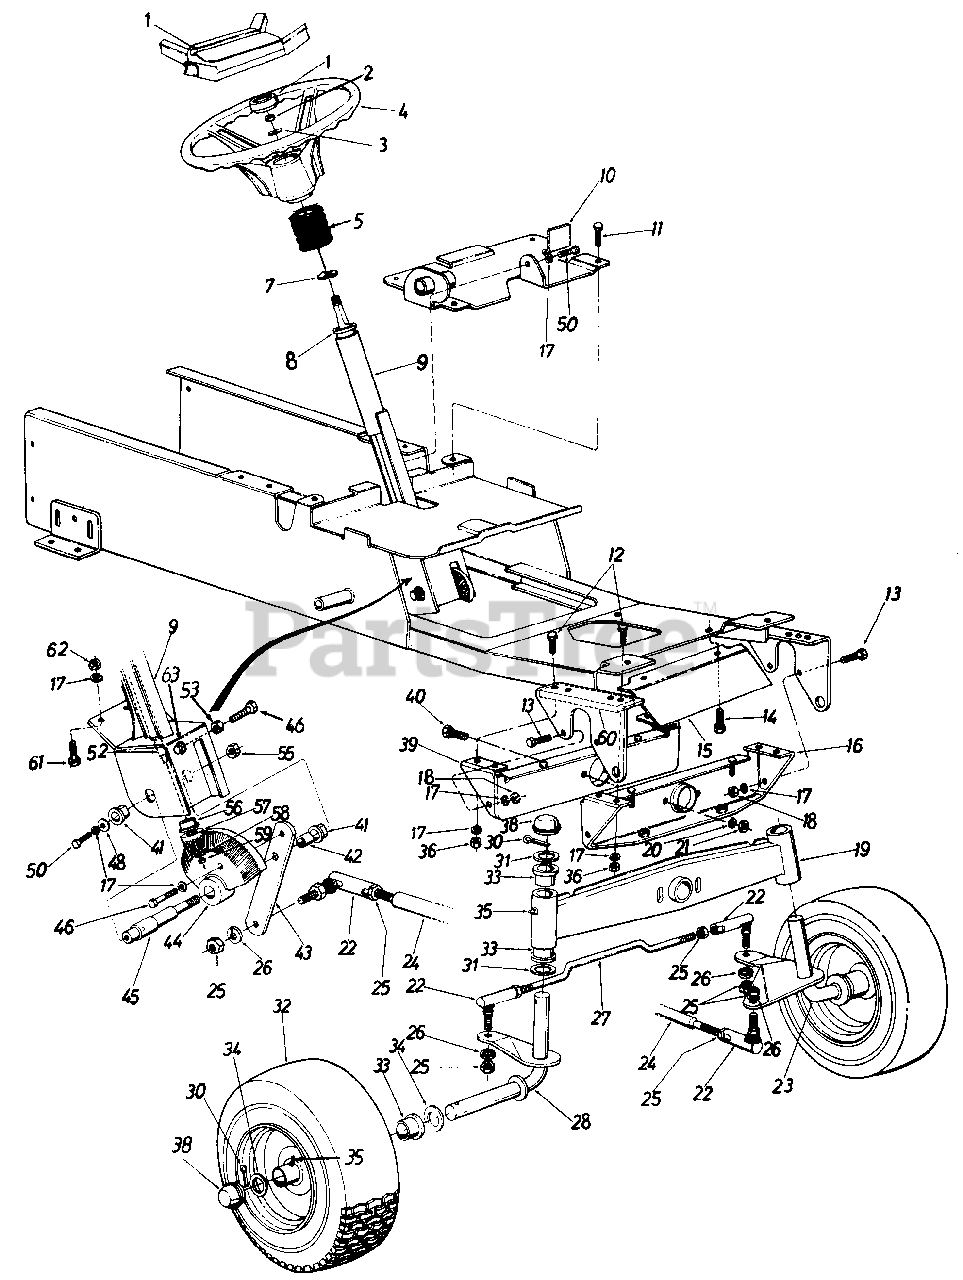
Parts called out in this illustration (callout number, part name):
1	Steering Wheel Cap
2	Hex Cent. L-Nut 5/16-24 Thd.
3	Bell-Wash. 5/16" I.D.
4	Steering Wheel
5	Steering Bellow
7	Wave Wash. .660" I.D. x .88" O.D.
8	Ball Brg. .63" I.D. x 1.38" O.D.
10	Dash panel Base Plate Ass'y.
11	Hex Self-Tap Scr. 3/8-16 x .75" Lg.
12	Hex Bolt 3/8-16 x 1.50" Lg.
13	Hex Bolt 3/8-16 x 1.00" Lg.
14	Hex Wash. S.F. Tap Scr. 3/8-16 x 1.25" Lg.
18	Hex Nut 3/8-16 Thd.
19	Pivot Bar Ass'y.
20	Bell-Wash. 3/8" I.D.
21	Hex Cent. L-Nut 3/8-16 Thd.
22	Drag Link End
23	Axle Ass'y. - L.H.
24	Drag Link
25	Hex Nut 1/2-20 Thd.
26	L-Wash. 1/2" I.D.
27	Tie Rod
28	Axle Ass'y. - R.H.
30	Cotter Pin 3/16" Dia. x 1.50" Lg.
31	Fl-Wash. 1.00" I.D. x 1.62" O.D.
33	Flange Brg. 1" I.D.
34	Fl-Wash. 1" I.D. x 1.25" I.D.
35	Grease Fitting
36	Hex Nut 3/8-16 Thd.
38	Dust Cover
41	Flange Brg. w/Flats .753" I.D.
42	Steering Gear Shaft Spacer
43	Steering Arm
44	Bevel Gear
45	Steering Gear Shaft
46	Hex Bolt 3/8-16 x .150" Lg.
48	Fl-Wash. .406" I.D. x 1.25" O.D.
50	Hex Bolt 3/8-16 x .75" Lg.
52	Steering Shaft
53	Hex Jam Nut 3/8-16 Thd.
55	Hex Ins. L-Nut 1/2-20 Thd.
56	Hex Flange Brg. .630 I.D.
57	Pinion Gear
58	Fl-Wash. 3/8" Dia.
59	Hex Cent. L-Nut 5/16-24 Thd.
62	Hex Nut 3/8-24 Thd.
